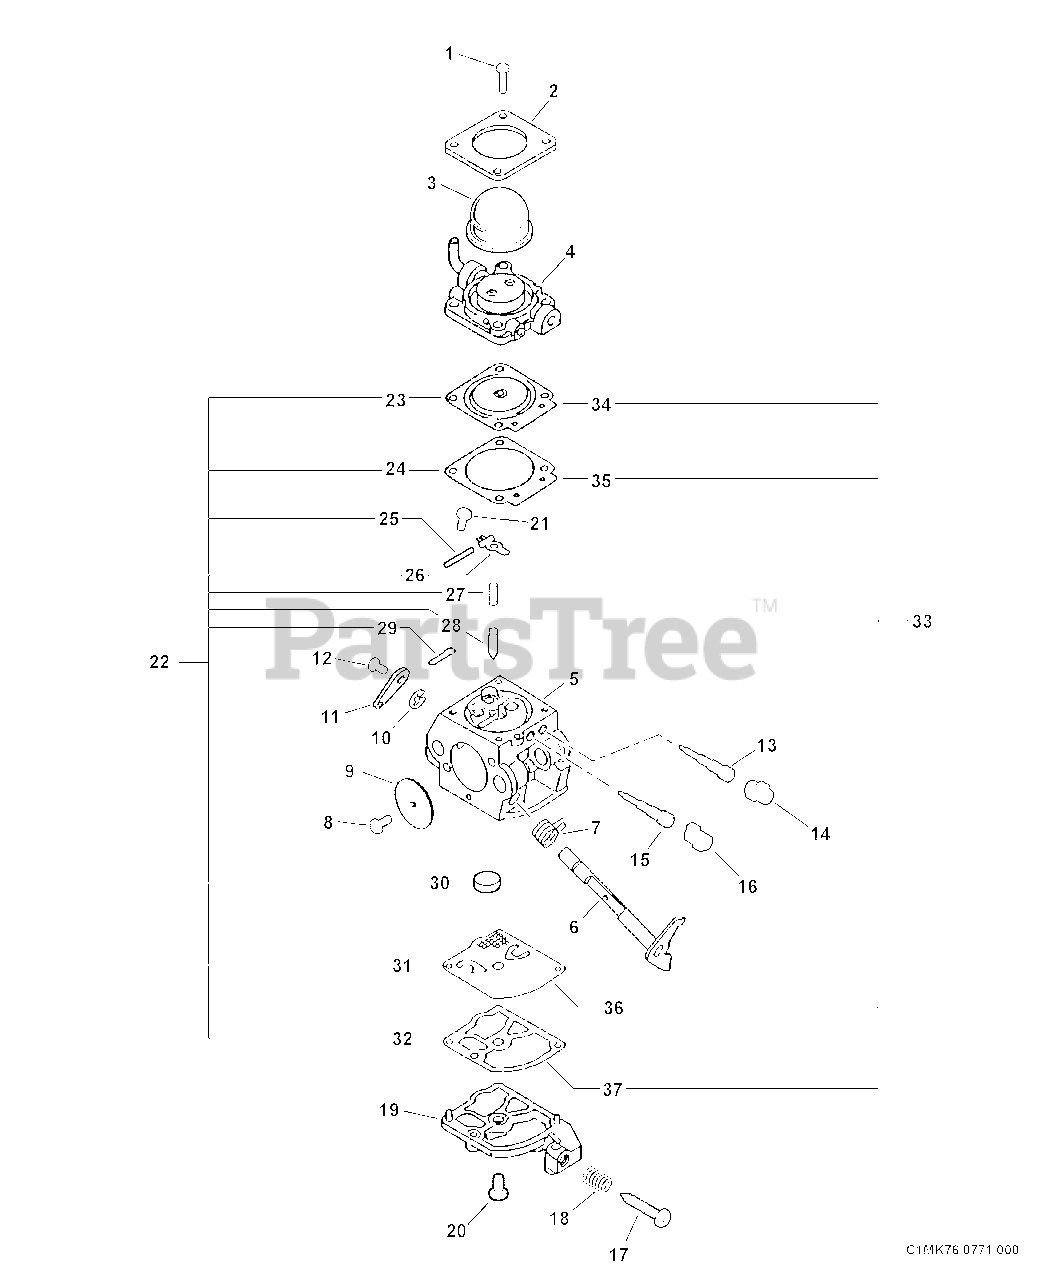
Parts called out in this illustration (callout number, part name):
2	RETAINER, PURGE BULB
3	BULB, PURGE
4	BODY ASSY, PURGE
5	BODY, CARBURETOR
6	SHAFT ASSY, THROTTLE
7	SPRING, THROTTLE RETURN
9	VALVE, THROTTLE
11	LEVER, THROTTLE
13	NEEDLE, HIGH SPEED
14	CAP, LIMITER - RED
15	NEEDLE, LOW SPEED
16	CAP, LIMITER - WHITE
18	SPRING, IDLE ADJUST
19	COVER, PUMP
22	REPAIR KIT
23	DIAPHRAGM, METERING
24	GASKET, METERING
25	PIN, METERING LEVER
26	LEVER, METERING
27	SPRING, METERING LEVER
28	VALVE, INLET NEEDLE
29	PLUG, WELCH
30	STRAINER
31	DIAPHRAGM, PUMP
32	GASKET, PUMP
33	GASKET / DIAPHRAGM KIT
34	DIAPHRAGM, METERING
35	GASKET, METERING
36	DIAPHRAGM, PUMP
37	GASKET, PUMP
